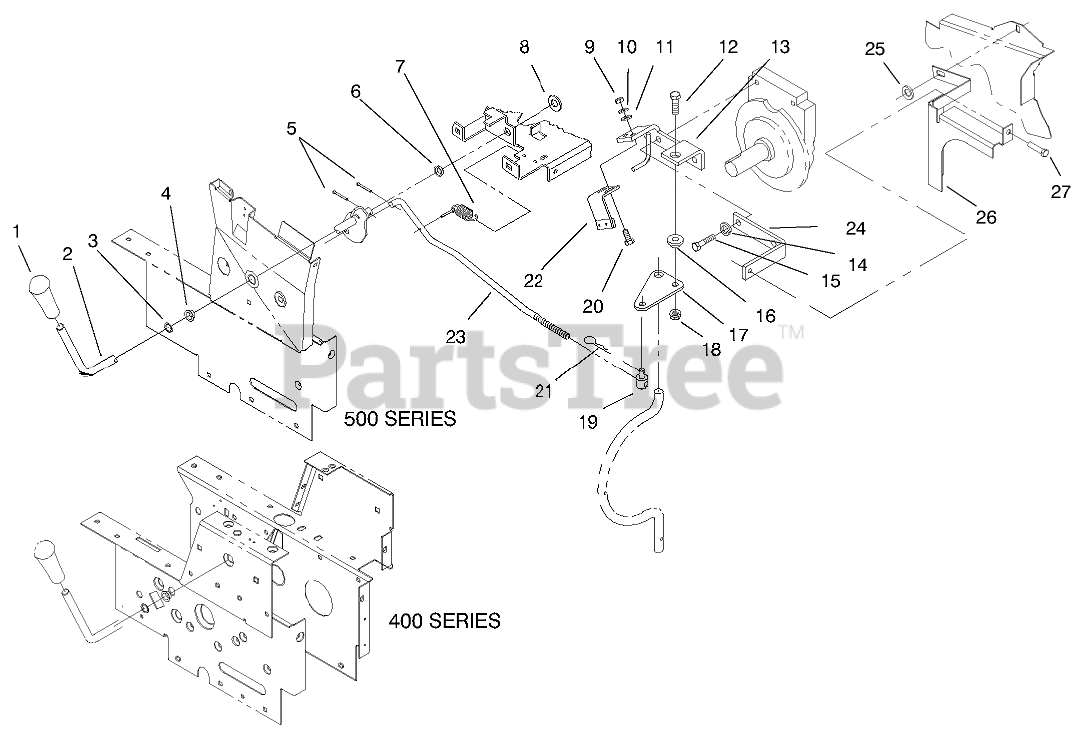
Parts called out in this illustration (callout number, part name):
2	PTO CLUTCH LEVER ASM
3	RING-EXT GRIP
4	BUSHING-NYLINER
5	PIN-COTTER
6	NYLINER BUSHING
7	SPRING
8	SHIM-WASHER
9	NUT-JAM
10	WASHER-LOCK
11	WASHER-FLAT
12	SCREW-HH
13	BRCKET-ENGINE (BLACK)
14	WASHER-LOCK
15	SCREW-HH
16	SPACER-LIFT LINK
17	PLATE
18	NUT-LOCK, NI
19	TRUNNION
20	SCREW-CARR
21	PIN-HAIR
22	BRAKE ASM
23	ROD-PTO CLUTCH
